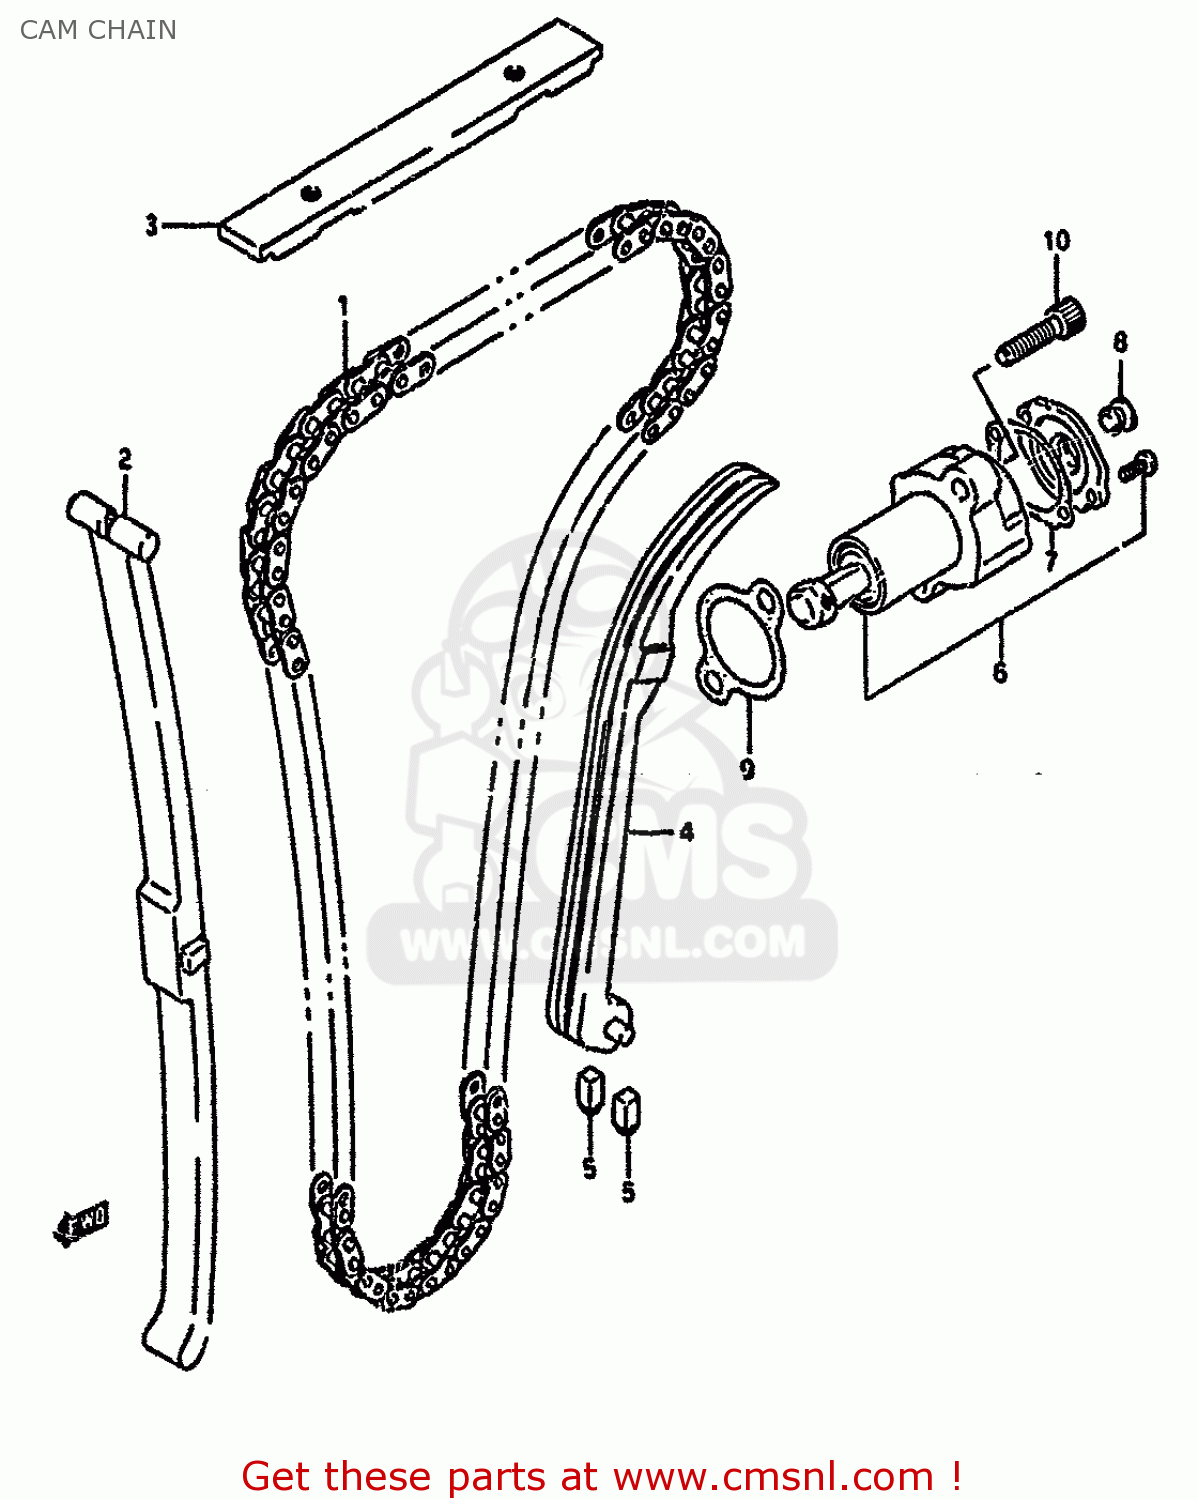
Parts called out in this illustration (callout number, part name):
1	CHAIN,CAMSHAFT DRIVE
2	GUIDE,CAM CHAIN NO.1
3	GUIDE,CAM CHAIN NO.2
4	TENSIONER,CAM CHAIN
5	CUSHION,CAM CHAIN TENSIONER
6	ADJUSTER ASSEMBLY,TENSIONER
7	GASKET,ADJUSTER CAP (NAS)
8	PLUG,ADJUSTER
9	GASKET,TENSIONER ADJUSTER (NAS)
10	BOLT
